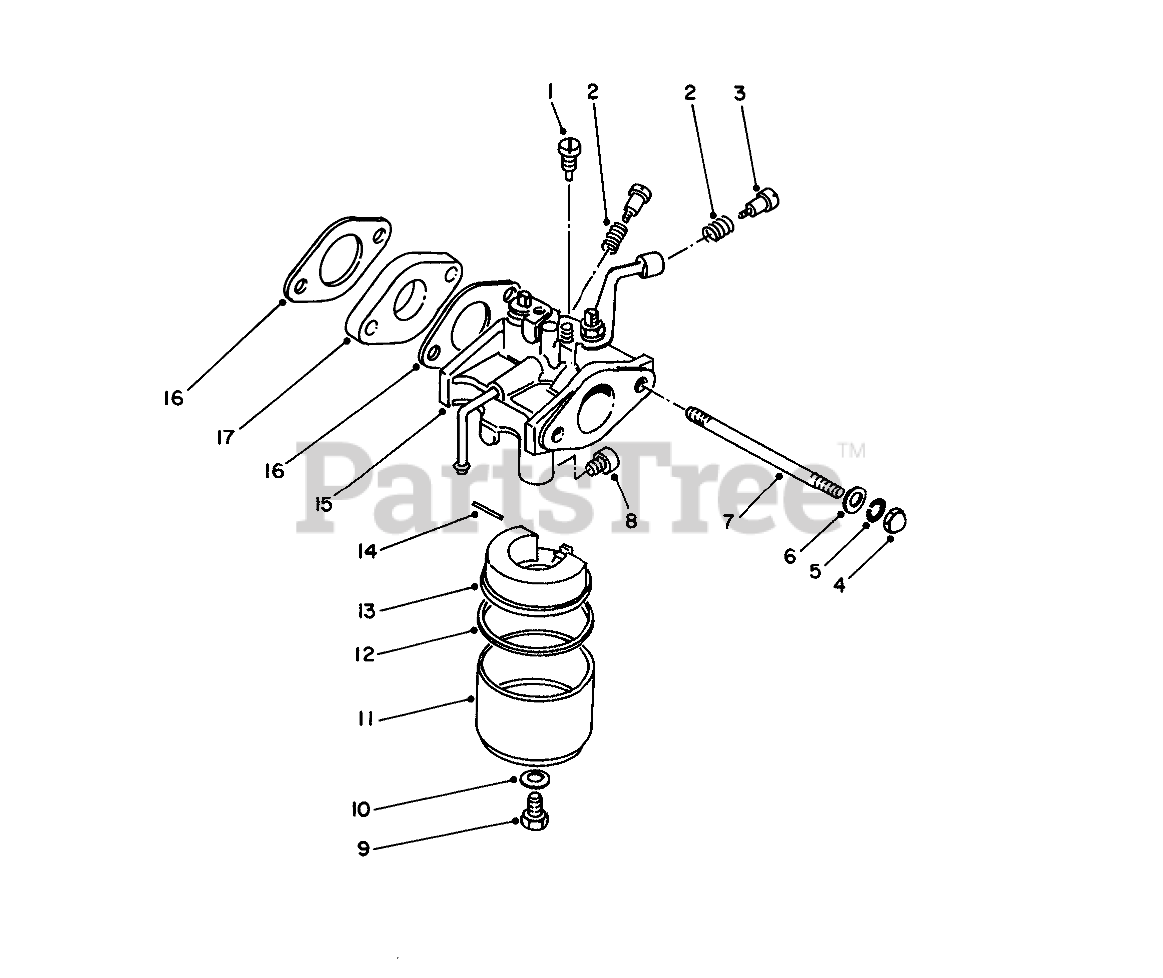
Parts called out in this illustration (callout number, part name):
1	PILOT JET
2	SPRING
3	SCREW
5	Washer-Lock
6	Washer
7	Stud Bolt
10	GASKET
11	Bowl-Float
12	GASKET
13	FLOAT
14	Pin
15	Carburetor Assembly (Incl. Ref . #1-14 & 16-18)
16	GASKET
17	Insulator
